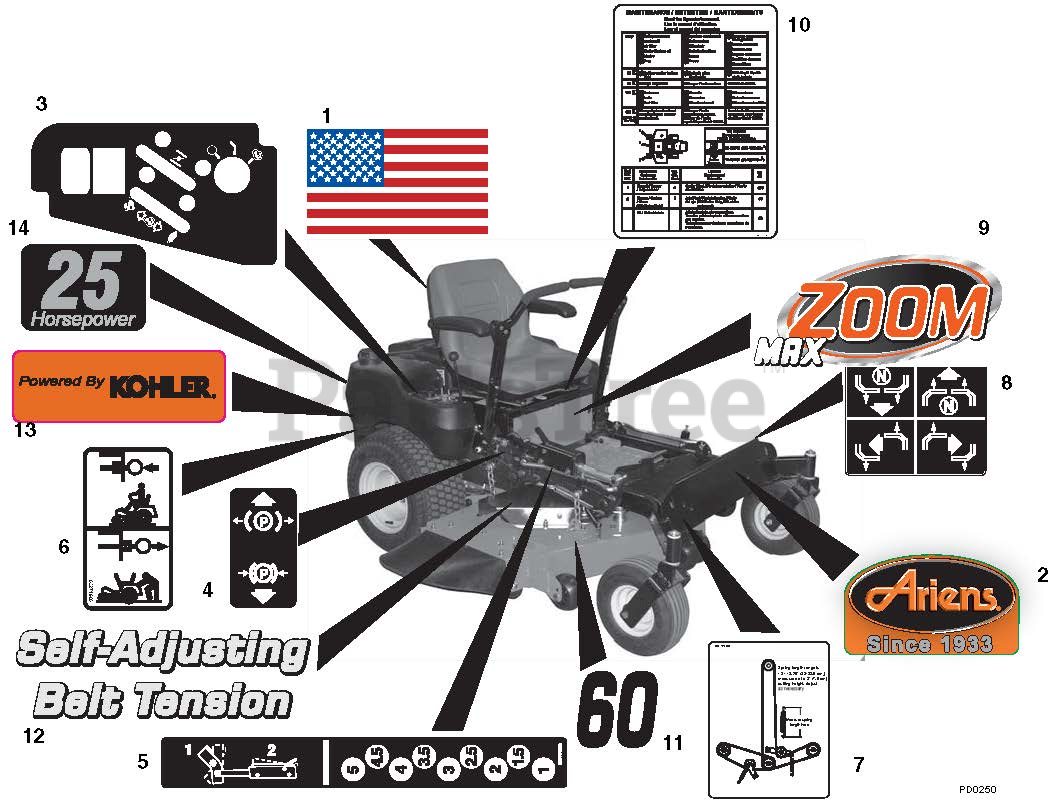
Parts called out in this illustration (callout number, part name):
1	DECAL, AMERICAN FLAG
2	DECAL, ARIENS SINCE 1933-LARGE
3	DECAL, CONTROL PANEL COMPACT Z
4	DECAL, PARKING BRAKE LEVER
5	DECAL, HEIGHT OF CUT COMPACT-Z
6	DECAL, TRANSMISSION DISCONNECT
7	DECAL, BELT DIAGRAM
8	DECAL, INSTRUCTIONAL-STEERING
9	DECAL, MAX ZOOM
10	DECAL-MAINTENANCE INSTRUCTIONS
11	DECAL, 60"
11	DECAL, "52" (PROZOOM DECK)
12	DECAL, DECK FEATURE
13	DECAL, POWERED BY KOHLER
14	DECAL, 25HP
